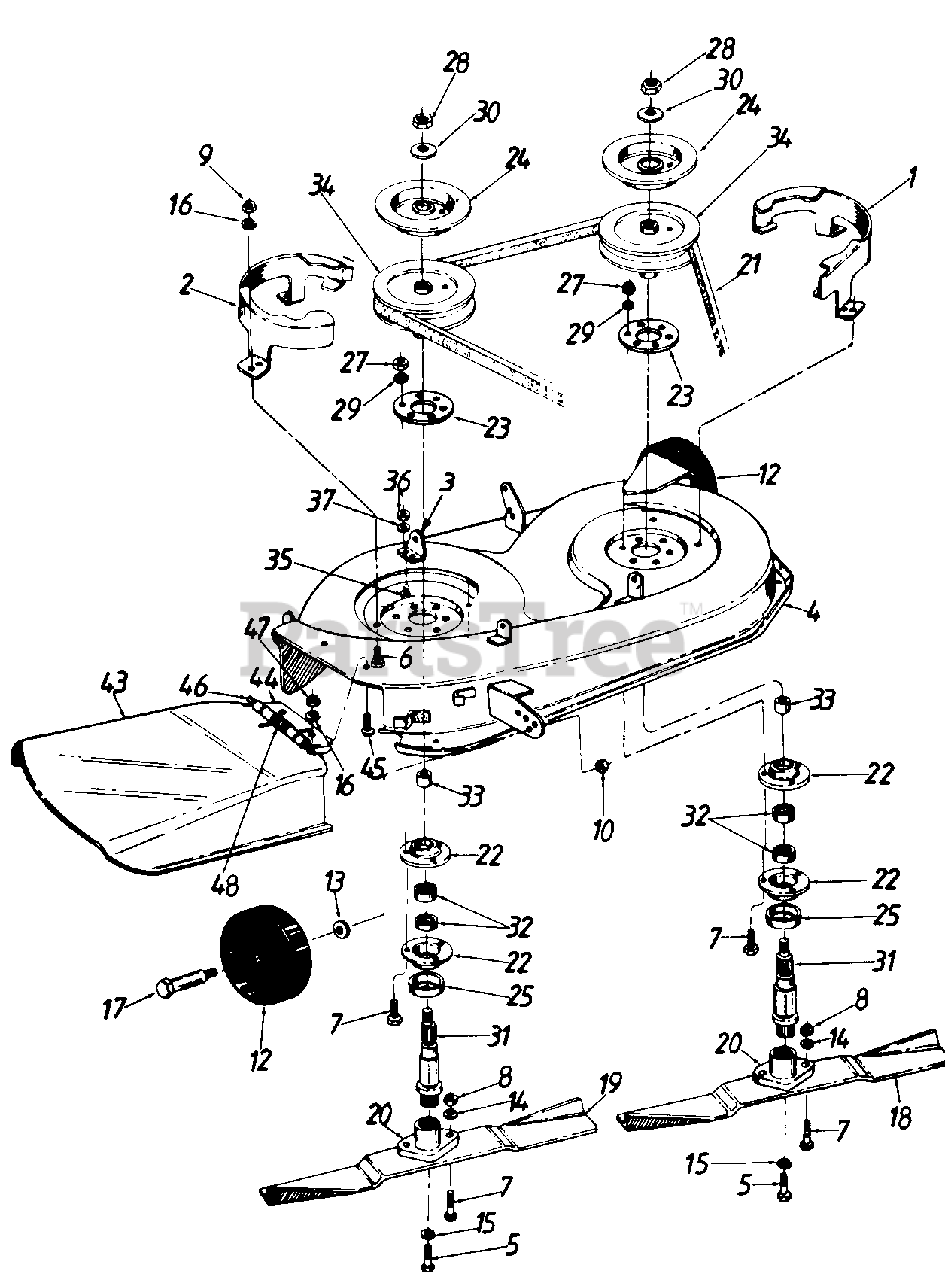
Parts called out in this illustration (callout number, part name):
5	Hex Bolt 3/8-24 x 1.0" Lg.
6	Hex Bolt 1/4-28 x .62" Lg.
7	Hex Bolt 5/16-24 x 1.0" Lg.
8	Hex Nut 5/16-24 Thd.
9	Hex Nut 1/4-28 Thd.
10	Hex L-Nut 3/8-16 Thd.
13	Bell-Wash. .380" I.D. x .88
14	L-Wash. 5116" I.D.
15	L-Wash. 318" I.D. H.D.
16	Bell-Wash. .265" I.D. x .75
17	Shld. Bolt .498" Dia. x 1.53 Lg.
18	L.H High-Lift Blade
19	R.H. High-Lift Blade
20	Blade Adapter
21	V-Belt
22	Bearing Housing
23	Reinforcement Plate
24	Brake Disc
25	Bearing Shield
27	Hex Nut 5/16-24 Thd.
28	Hex Jam Nut 5/8-18 Thd.
29	L-Wash. 5/16" I.D.
30	L-Wash. 5/8" I.D.
31	Blade Spindle
32	Ball Bearing
34	5" Dia. Pulley
35	Hex Scr. 1/4-20 x .62" Lg.
36	Hex Nut 1/4-20 Thd.
37	L-Wash. 1/4" I.D.
43	Chute Ass'y.
44	Chute Bracket
45	Truss-Mach. Scr. 1/4-20 x .75" Lg.
47	Hex Jam Nut 1/4-20 Thd.
48	Torsion Spring 1.14" Lg.
